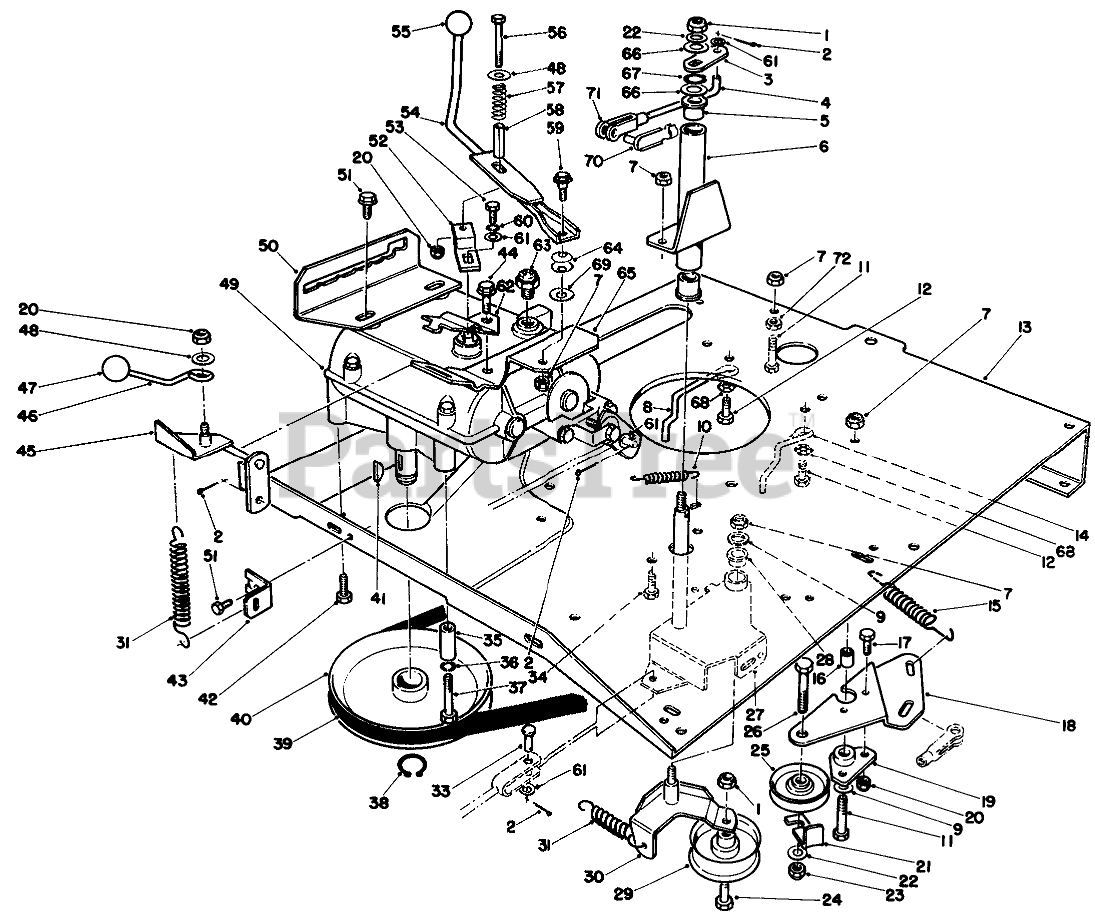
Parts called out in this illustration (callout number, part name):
1	NUT-LOCK, NI
2	PIN-COTTER
3	Flat-Deck Engage
4	LINK-DECK ENGAGE
5	BUSHING-FLANGE
6	Pivot Tube W.A. (Incl. Ref. #5)
7	NUT-LOCK, NI
8	ENG BELT GUIDE R.
9	WASHER-PLAIN
10	SPRING-RETURN, BRAKE
11	SCREW-HH
12	SCREW-HH
13	PLATE-ENGINE
14	GUIDE-ENG. BELT L.
15	SPRING-TRACTION
16	SPACER-PIVOT
17	SCREW-HH
18	Plate-Idler Mount
19	MOUNT-TRACTION PIVOT
20	NUT-LOCK, NI
21	RETAINER-BELT
22	WASHER-FLAT
23	NUT-LOCK, NI
24	SCREW-HH
25	PULLEY-IDLER
26	SCREW-HH
27	Bracket-Idler Arm (Incl. Ref. #28)
28	BUSHING-FLANGE
29	PULLEY-IDLER
30	Idler-Plate, Mount
31	SPRING-IDLER
32	PIN-COTTER
33	PIN-CLEVIS
34	SCREW-HH
35	GUIDE-BELT
36	WASHER-LOCK
37	SCREW-HH
38	RING-SNAP, EXTERNAL
39	67BELT, TRACTION DRIVE
40	PULLEY
41	KEY-WOODRUFF
42	5/16-18 X 5/8 SEMS SC
43	BRKT-SPRING MT
44	SCREW-HWHTF
45	Lever W.A.-Deck Engage
46	ROD-ENGAGE
47	KNOB-CONTROL
48	WASHER-FLAT
49	TRANSMISSION
50	Gate-Shift
51	SCREW-HWHTF
52	LEVER-SHIFT
53	SCREW-HH
54	SHIFT LEVER WA
56	SCREW-HH
57	SPRING-COMPRESSION
58	SPACER-SPLIT
59	SCREW-SHOULDER
60	WASHER-LOCK
61	WASHER-FLAT
62	BRKT-DECK ENG UPPER
63	NEUTRAL SWITCH
64	WASHER-BELLEVILLE
65	BRKT-DECK ENG. SHIFTER
66	WASHER
67	RING-RETAINING
68	WASHER
69	THRUST WASHER
70	CLEVIS PIN ASM
71	CLEVIS-ADJ
72	NUT-JAM
